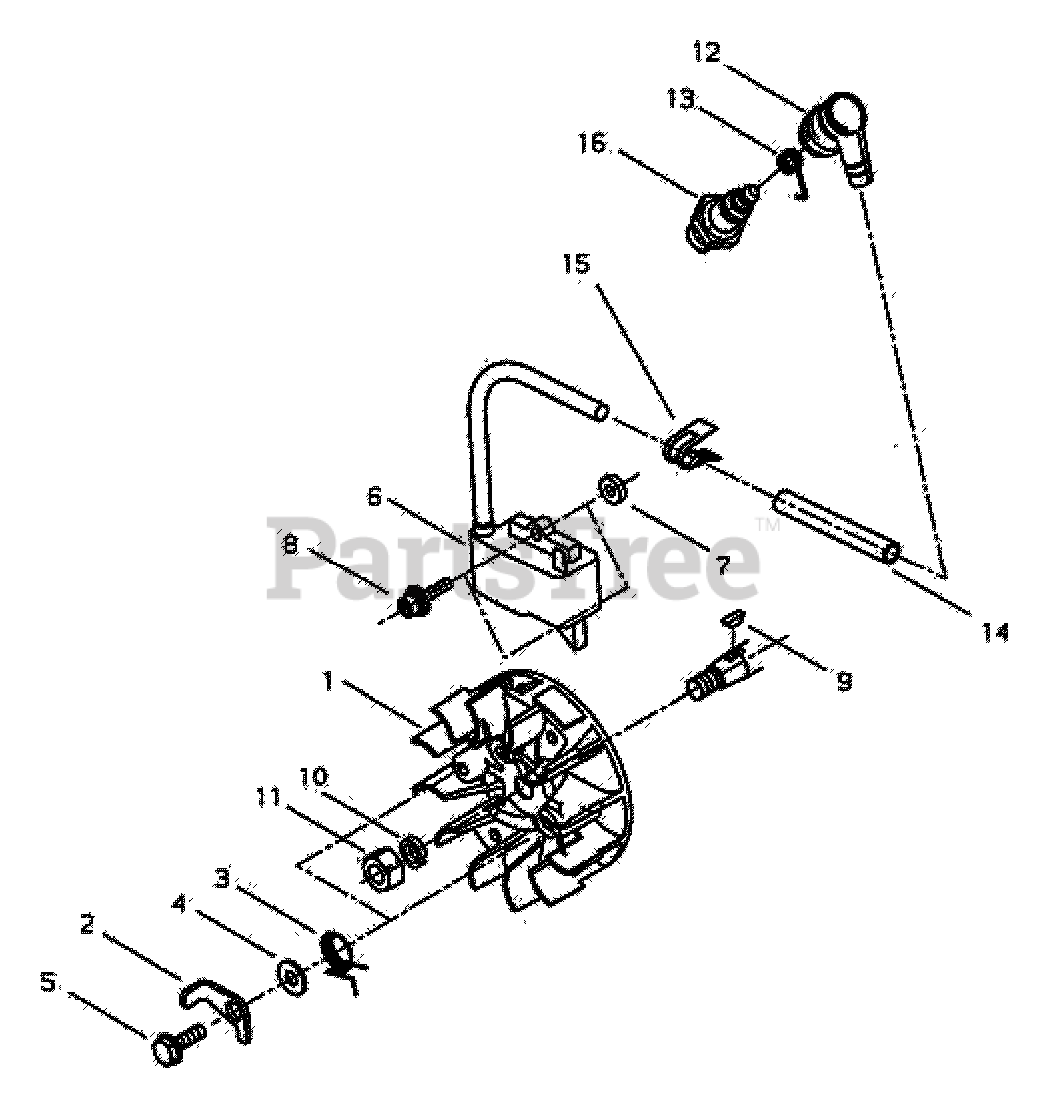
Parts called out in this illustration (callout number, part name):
1	FLYWHEEL
2	PAWL, STARTER
3	SPRING, RETURN
4	WASHER
5	BOLT
6	IGNITION COIL ASSY
7	INSULATOR
8	SCREW - 4X20
9	KEY - 3X10
10	LOCKWASHER - 8
11	NUT
12	CAP, SPARK PLUG
13	TERMINAL, SPARK PLUG CAP
14	TUBE
15	CLIP
16	SPARK PLUG -- BPMR-7A
